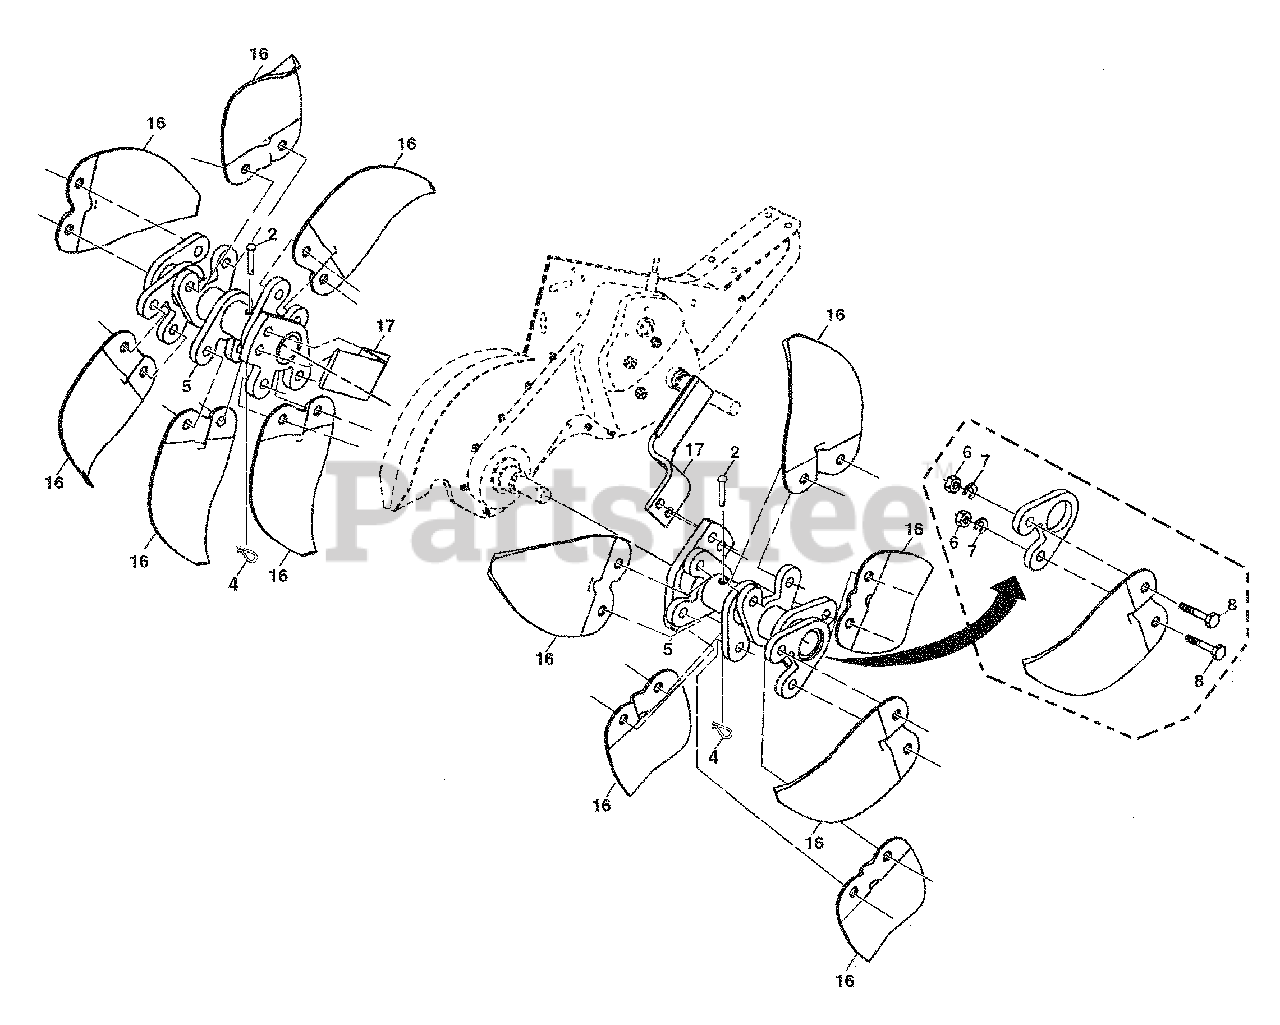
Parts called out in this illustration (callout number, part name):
2	Pin, Shear
4	Clip, Hairpin
5	Hub Assembly
6	Nut, Hex 3/8-24
7	Washer, Lock 3/8
8	Bolt, Hex 3/8-24 x 1
16	Tine, Spade
17	Tine, Cleaning
